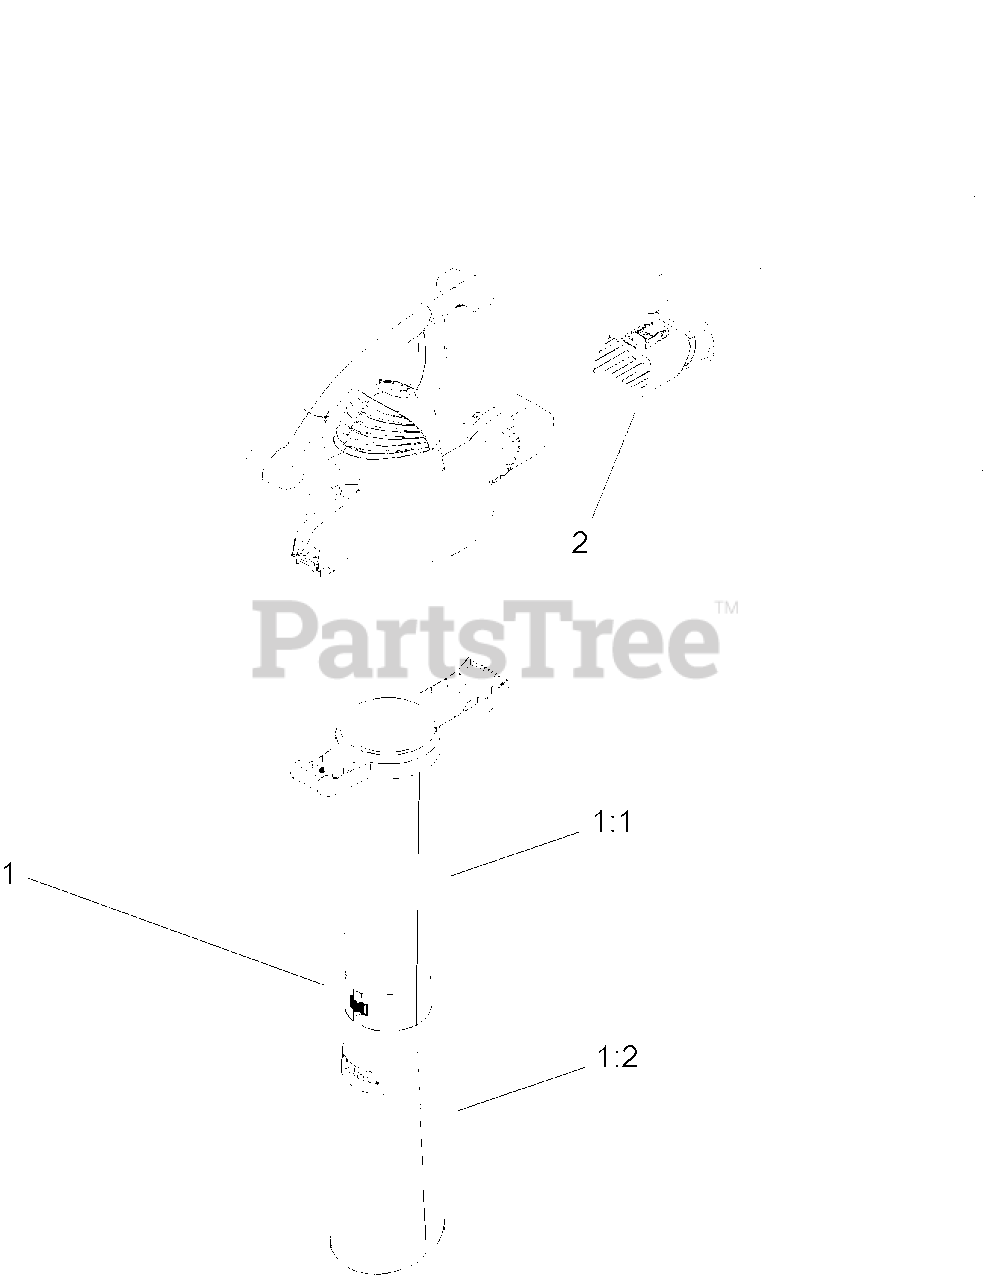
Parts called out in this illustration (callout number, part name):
1	Vac Tube ASM (Not serviced separately)
1:1	TUBE-VAC, UPPER
1:2	TUBE-VAC, LOWER
2	BAG ASM
